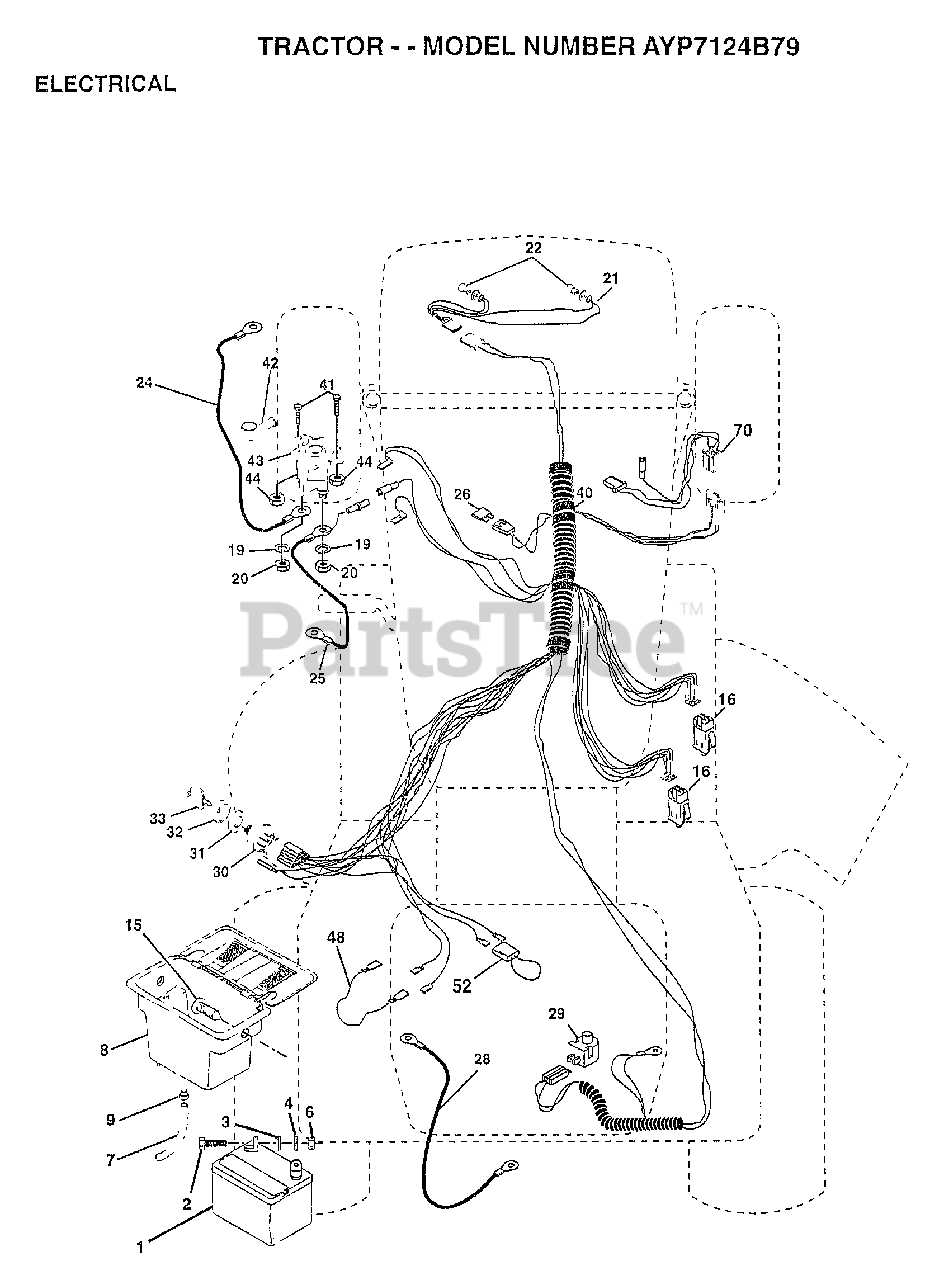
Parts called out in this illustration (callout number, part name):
2	BOLT LT
3	WASHER
4	LOCKWASHER
7	TUBE T
8	"CASE,BATTERY.MECH"
9	HOSE CLAMP T
15	FASTNER.SNAP-IN
16	SWITCH INTERLOCK
20	NUT
21	"HARNESS,LIGHT SOC"
22	HEADLAMP BULB
24	"CABLE T, BATTERY"
25	CABLE.BTRY.6GA.RD
26	FUSE HYT
28	CABLE T
29	SWITCH SEAT
30	SWITCH IGN 4POS
31	NUT IGNITION
32	COVER KEY SWITCH
33	KEY
40	HARNESS-IGNITION
41	BOLT HXHD FIN
44	NUT HXKEP 1/4X20
48	ADAPTER AMMETER
52	PROTECTION LOOP
70	HARNESS ENG DUAL
